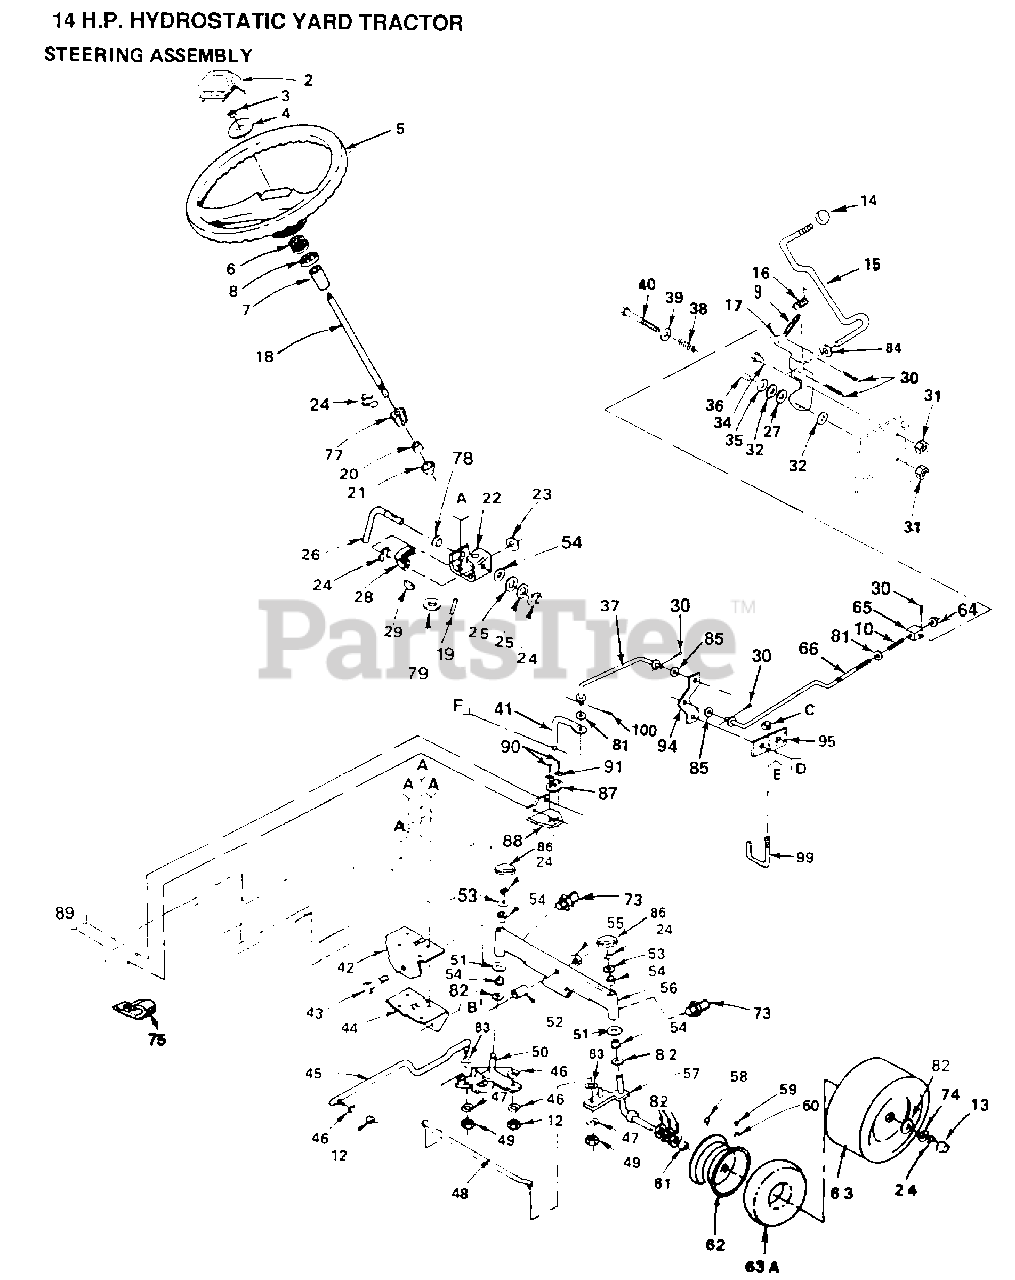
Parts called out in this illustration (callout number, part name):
4	WASHER
6	ADAPTER LT
9	SPRING.RETAINER
10	SPRING GTV
13	HUB CAP
14	KNOB.DUCKHEAD.1/2
15	ROD.YTH
16	SPRING TORSION
17	BRKT CONTROL HYT
18	STEERING SHAFT T
20	SHAFT SPACER LT
21	BUSHING
23	WASHER D
24	RING
25	WASHER .T
26	ROD STEERING T
27	WASHER HYT
28	GEAR.SECTOR.HYT
29	KEY-WOODRUFF LT
30	COTTER PIN
32	WASHER FRIC HYT
34	BOLT HYT
35	WASHER D
36	SPACER HYT
37	LINK CONTROL
38	SPRING HYT
39	WASHER
40	BOLT - HEX 3/8 - 16 X 3
41	ARM ASM PUMP
42	SUPPORT-SADDL T
43	BOLT LT
44	SUPPORT.SADDLE.FT
46	LOCKWASHER
47	LOCKWASHER
48	ROD TIE
49	NUT.LOCK.5/16-24
50	SPINDLE-LH LT
51	WASHER
52	BEARING
53	WASHER .T
54	COL. SRTG. BEAR.
55	"NUT-LOC,FLANGE LT"
56	FRONT AXLE
58	FITTING LT
59	VALVE STEM LT
60	VALVE CAP
61	"FLANGE, BEARING"
63A	TUBE.5.3/4.5/6
64	NUT
65	TRUNION HYT
66	ROD ADJ CONTROL
73	ZERK M
74	WASHER
75	INSUL CLIP T
77	GEAR PINION T
78	NYLINER T
81	WASHER T
82	WASHER
83	WASHER M
84	WASHER
85	WASHER T
86	CAP
87	GUIDE CONTROL
88	BRKT
89	SCREW
90	SCREW
91	WASHER
94	BELLCRANK
95	BRKT BELLCRANK
99	KEEPER
100	RETAINER M
